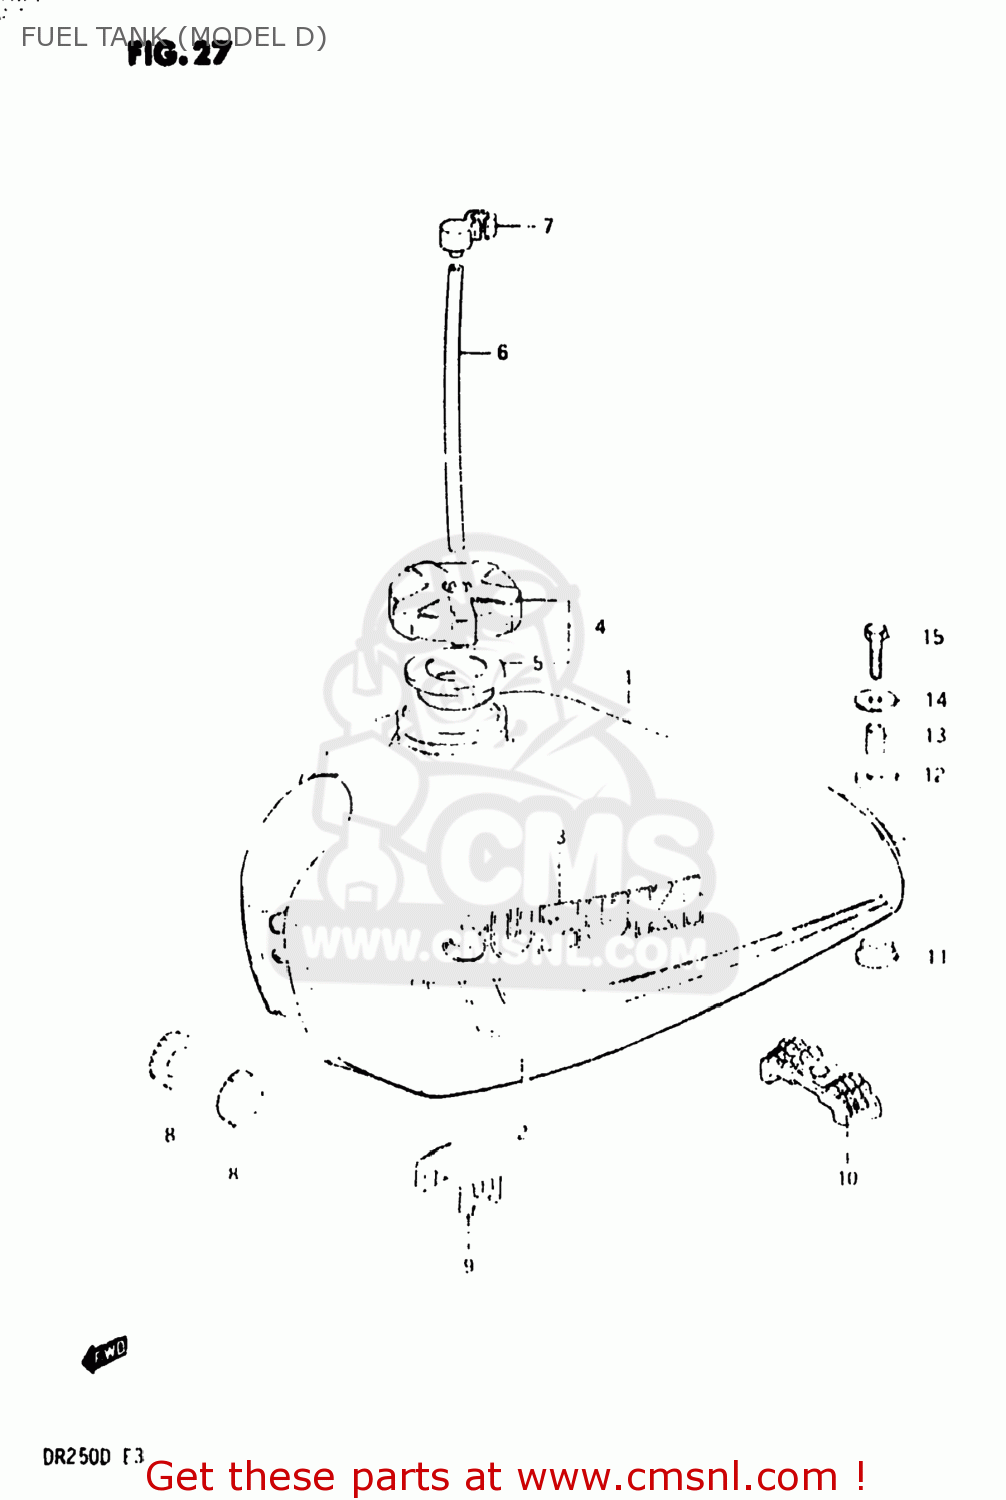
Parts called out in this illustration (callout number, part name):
1	TANK ASSEMBLY,FUEL
2	TAPE SET,FUEL TANK
3	EMBLEM
4	CAP SET,FUEL TANK
5	GASKET (NAS)
6	HOSE
7	CLAMP,FUEL TANK BREATHER HOSE
8	CUSHION
9	CUSHION,TANK UPR FR
10	CUSHION,FUEL TANK,REAR
11	CUSHION
12	CUSHION
13	SPACER(8.5X12X19)
14	WASHER (8.5X29X1.6)
15	BOLT (8X30)
